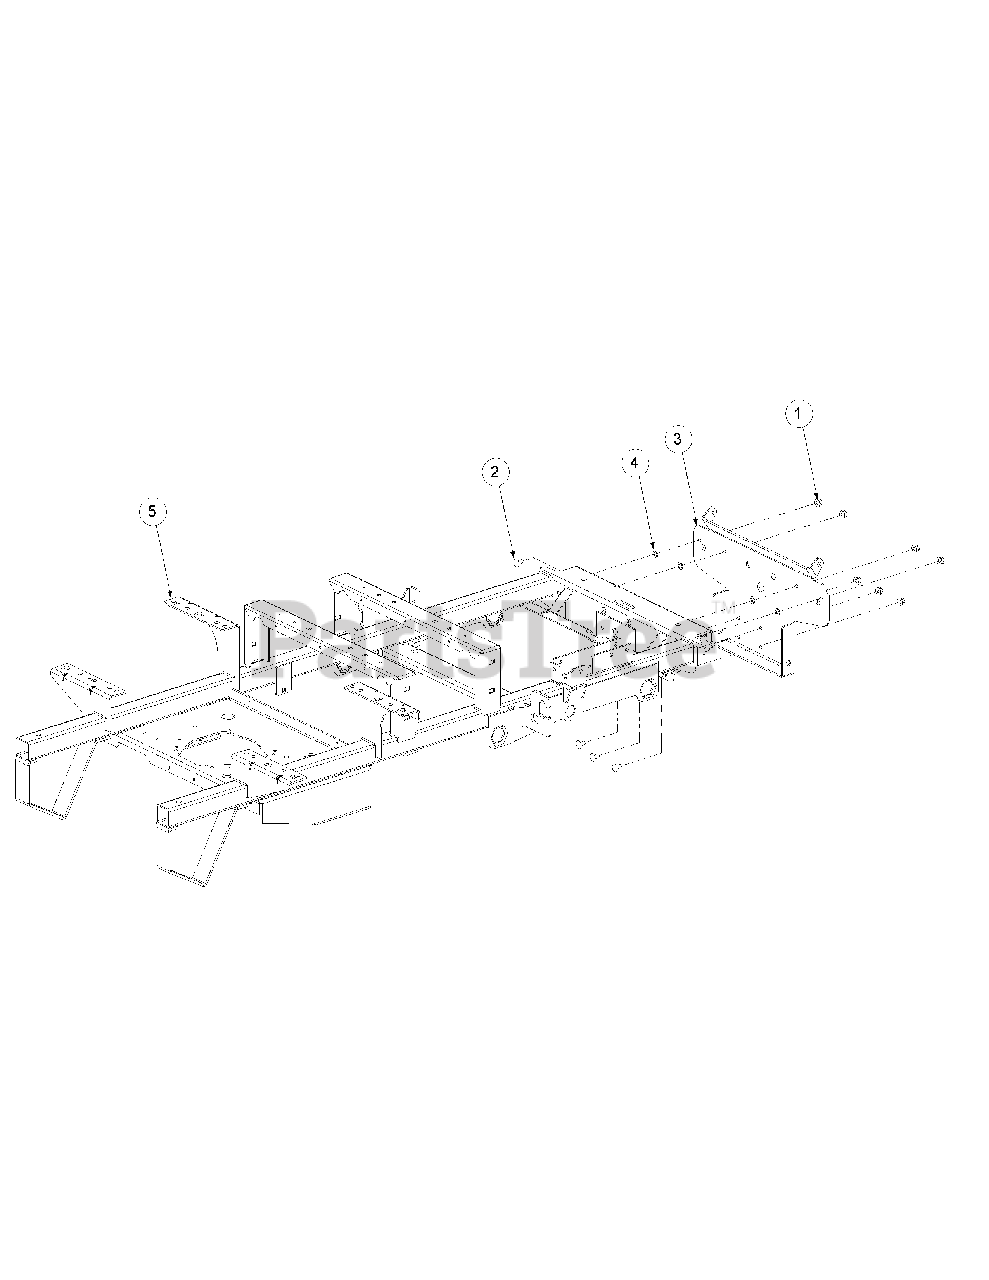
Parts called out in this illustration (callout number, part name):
1	Hex Nut, 3/8-16 Flange Lock
2	Carriage Bolt, 3/8-16 x .75 Long
3	Bracket Assembly, Frame, Front
4	Push Retainer, 3/8"
5	Frame Assembly
